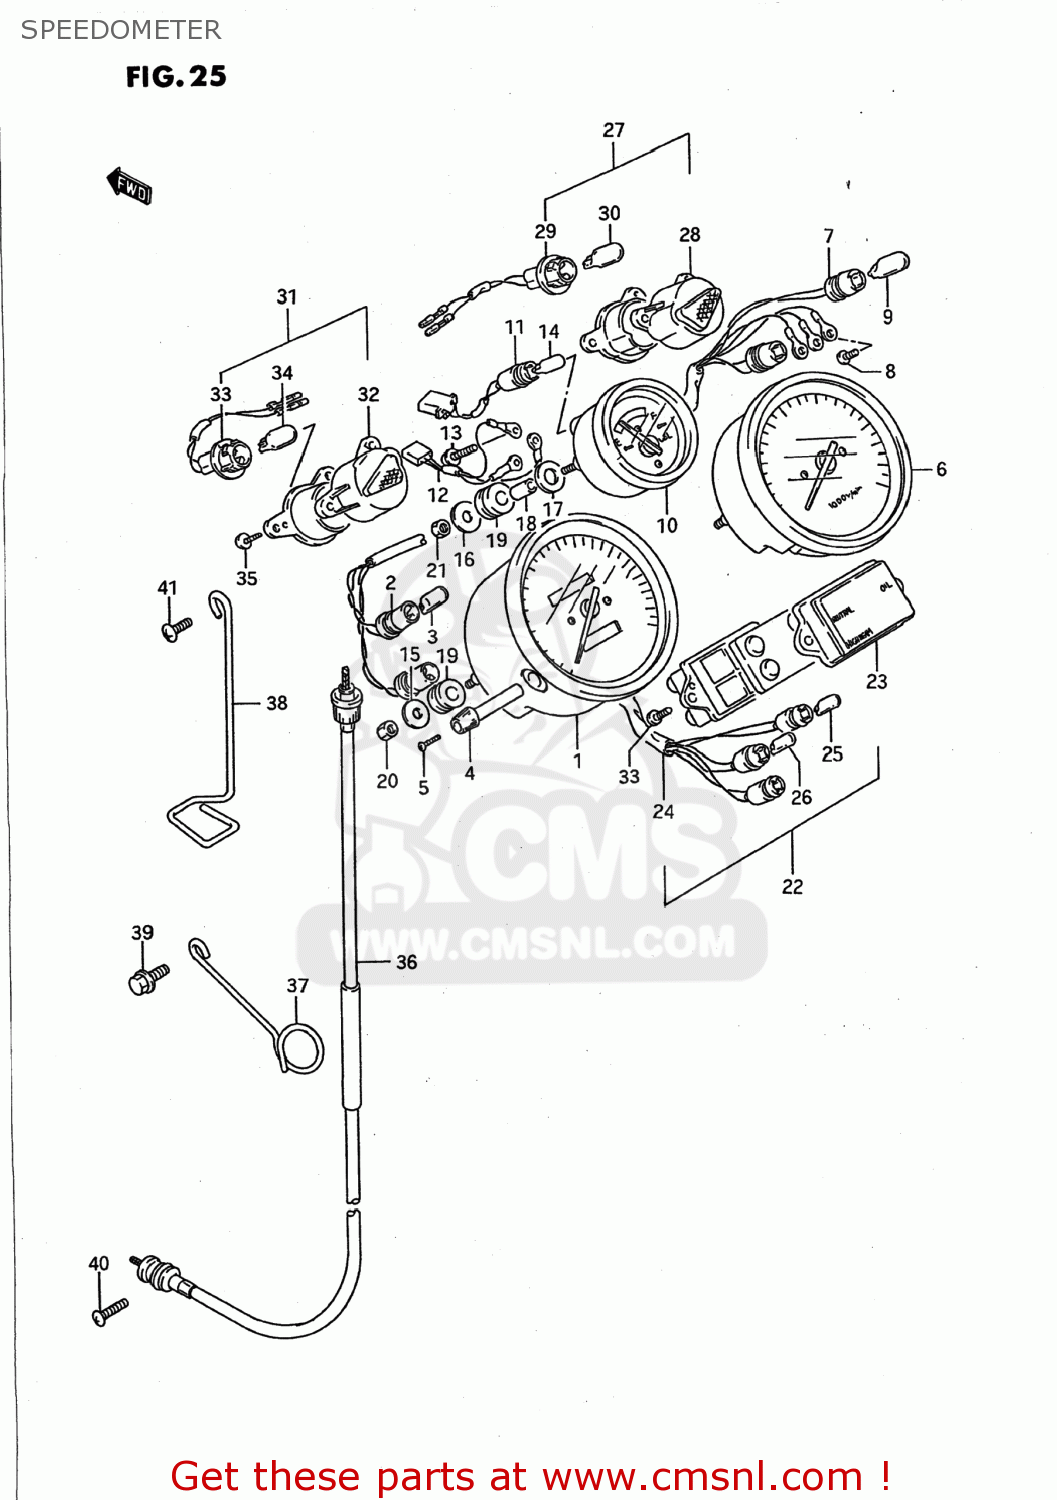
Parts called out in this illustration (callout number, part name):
1	SPEEDOMETER ASSEMBLY
2	SOCKET
3	BULB(12V1.7W,T10,WB121)
4	KNOB,TRIP
5	SCREW(2X6)
6	TACHOMETER ASSEMBLY
7	SOCKET
8	SCREW
9	BULB(12V1.7W,T10,WB121)
10	METER ASSY,FUEL
11	SOCKET
12	CORD ASSEMBLY
13	SCREW(3X22)
14	BULB(12V1.7W,T6.5)
15	WASHER(5.5X16X1.2)
16	WASHER (4X16X1.2)
17	WASHER(8.2X18X1.2)
18	SPACER (4.5X7.5X15)
19	CUSHION,TACHOMETER
20	NUT
21	NUT
22	BOX ASSY,PILOT LAMP
23	CASE,PILOT LAMP UPR
24	CORD ASSY
25	BULB(12V1.7W,T6.5)
26	BULB(12V3W,T6.5)
27	LAMP ASSEMBLY,TURN SIGNAL P
28	LENS,PILOT LAMP,R
29	SOCKET
30	BULB(12V3.4W,T10,BF175-01450A)
31	LAMP ASSY,TURNSIGNAL PILOT,L
32	LENS,PILOT LAMP,LEFT
33	SOCKET
34	BULB(12V3.4W,T10,BF175-01450A)
35	SCREW
36	CABLE ASSY,SPEEDOMETER
37	CLAMP,SPEEDOMETER CABLE
38	CLAMP,SPEEDOMETER CABLE
39	BOLT
40	SCREW
41	SCREW 5X12
